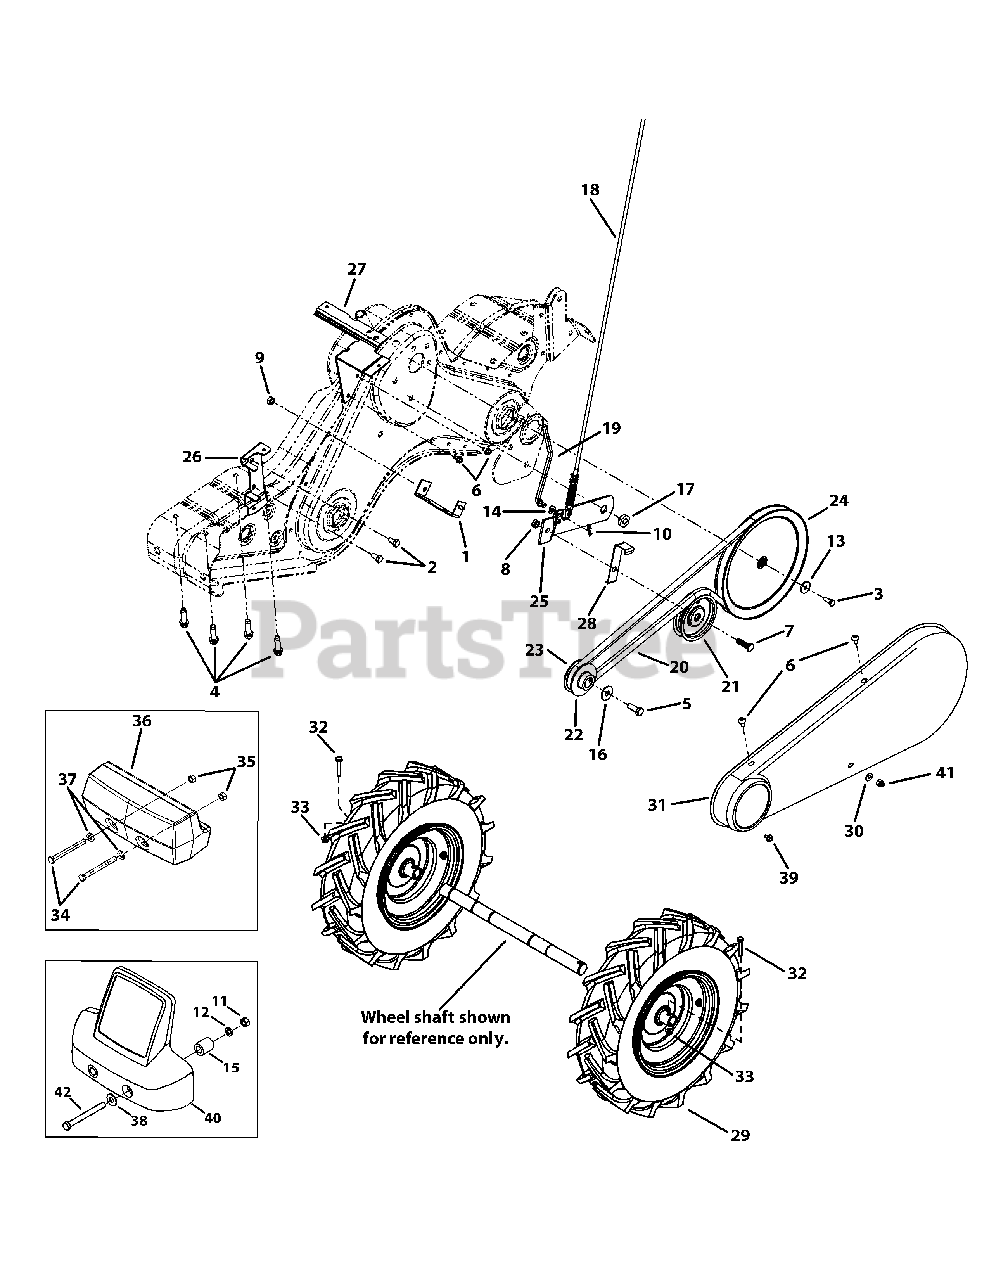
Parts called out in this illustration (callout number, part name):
1	Belt Cover Bracket Assembly
2	Hex Bolt, 5/16-24 x .625
3	Hex Bolt, 1/4-28 x .75"
4	Hex Washer Screw, 3/8-16 x 1.50"
5	Hex Bolt, 3/8-24 x 1.0
6	Hex Washer Screw
7	Hex Cap Screw, 3/8-16 x 1.25
8	Lock Jam Nut, 3/8-16
9	Flangelock Nut, 5/16-18
10	Internal Cotter Pin
11	Hex Nut, 1/2-20
12	Washer, Lock, 1/2
13	Flat Washer, .25 ID x .93 OD
14	Spring Washer, .317 ID x .625 OD
15	Hub, .636 ID x 1.00 OD x .94
16	Bell Washer, .396 ID x 1.14 OD
17	Shoulder Nut, 7/16-20
18	Clutch Cable
19	Idler Pulley Rod
21	Flat Idler w/ Flange, 3.75 OD
22	Outer Engine Pulley Half
23	Inner Engine Pulley Half
24	Input Pulley
25	Idler Bracket
26	Belt Keeper Bracket
27	Shift Cover Bracket
28	Idler Belt Keeper
29	Wheel Assembly, 16.0 x 4.6 x 8
30	Flat Washer, .271 ID x .630 OD
32	Hex Head Screw, 1/4-20
33	Flange Lock Nut, 1/4-20
34	Hex Bolt, 1/2-13 x 5.0
35	Flange Lock Nut, 1/2-13
36	Counterweight, 40 lbs.
37	Flat Washer
38	Washer, Flat, 1/2 x 1.25 x .100
39	Hex Screw, 1/4-20 x .375
40	Counterweight
42	Hex Head Screw, 1/2-13 x 5.50
